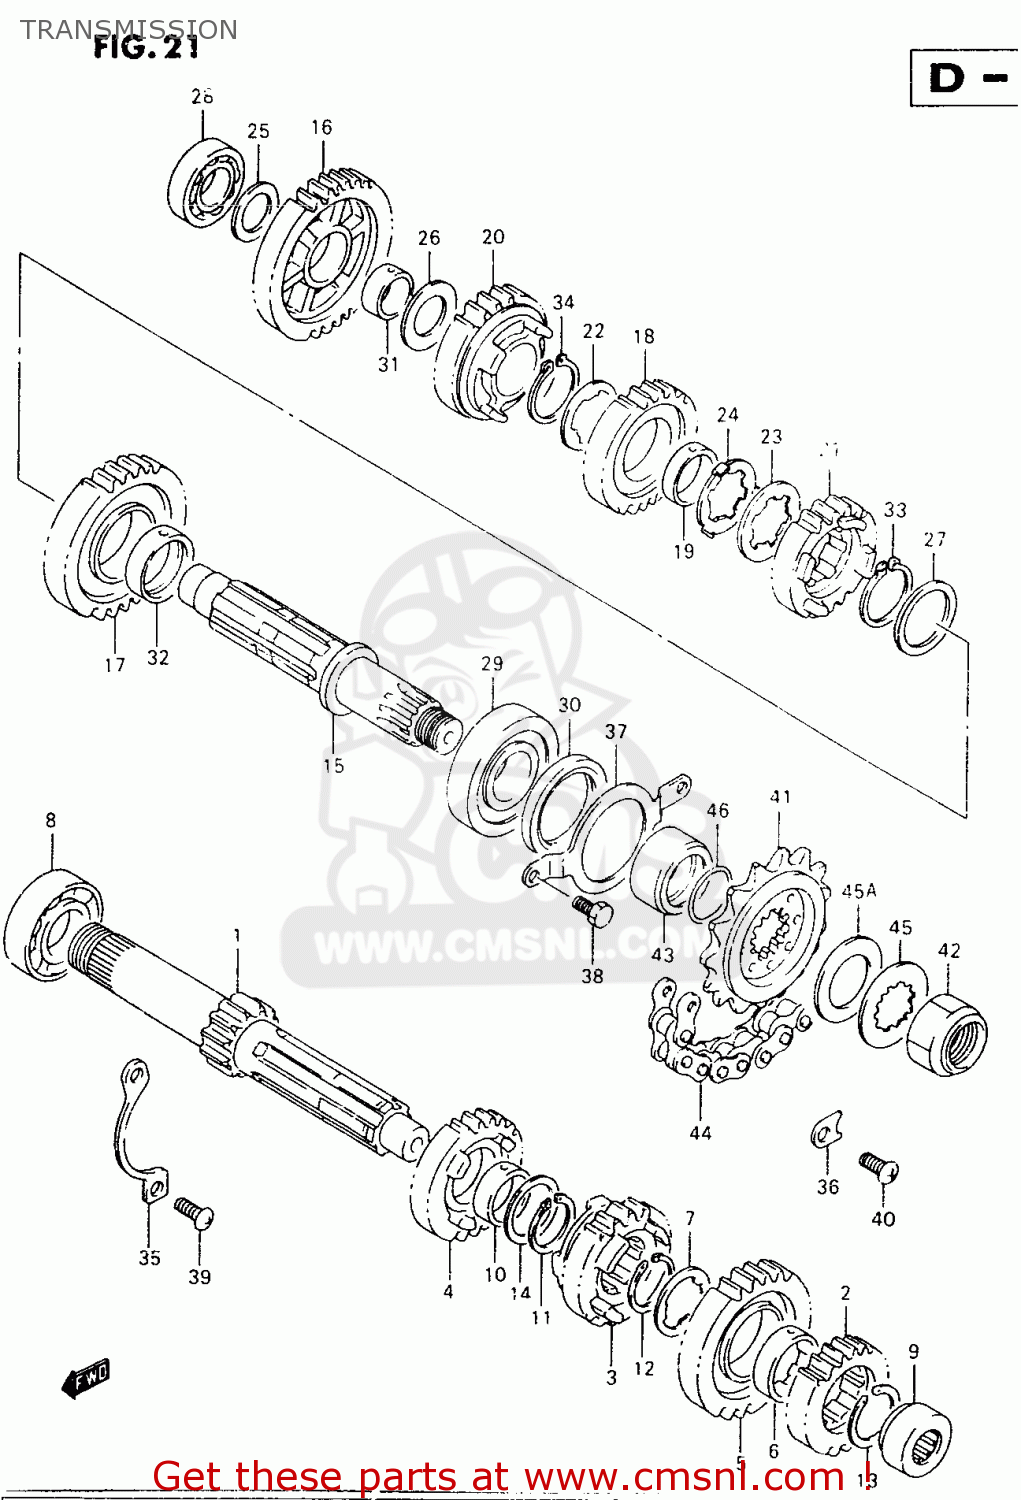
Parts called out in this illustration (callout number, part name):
1	SHAFT,COUNTER
2	GEAR,2ND DRIVE(NT:19)
3	GEAR,3RD DRIVE
4	GEAR,4TH DRIVE(NT:23)
5	GEAR,5TH DRIVE(NT:25)
6	BUSHING
7	WASHER,LOCK
8	BEARING(25X62X17)
9	BEARING(20X33X16)
10	BUSHING 25X29X10
11	RING,SNAP
12	RING,SNAP
13	CIRCLIP
14	WASHER
15	SHAFT,DRIVE
16	GEAR,1ST DRIVEN(NT:32)
17	GEAR,2ND DRIVEN(NT:30)
18	GEAR,3RD DRIVEN(NT:24)
19	BUSH
20	GEAR,4TH DRIVEN(NT:22)
21	GEAR,5TH DRIVEN(NT:20)
22	WASHER,LOCK
23	WASHER,LOCK
24	WASHER
25	SHIM(20X32X1)
26	SHIM(22X34X1)
27	SHIM(28X36X1)
28	BEARING(20X42X12)
29	BALL BEARING 25X62X17
30	SEAL,OIL(36X50X6)
31	BUSHING
32	BUSH(28X32X11)
33	CIRCLIP
34	CIRCLIP
35	RETAINER,CNTR SHAFT BEARING
36	RETAINER
37	RETAINER,DRIVE SHAFT OIL SEAL
38	BOLT
39	SCREW
40	SCREW
41	SPROCKET,ENGINE(NT:15)
42	NUT,ENGINE SPROCKET
43	SPACER,FR PULLEY
44	CHAIN(DID50VA2,116L)
45	WASHER,LOCK
45A	WASHER(25.2X42X3.2)
46	O RING(D:2.4,ID:23.7)
